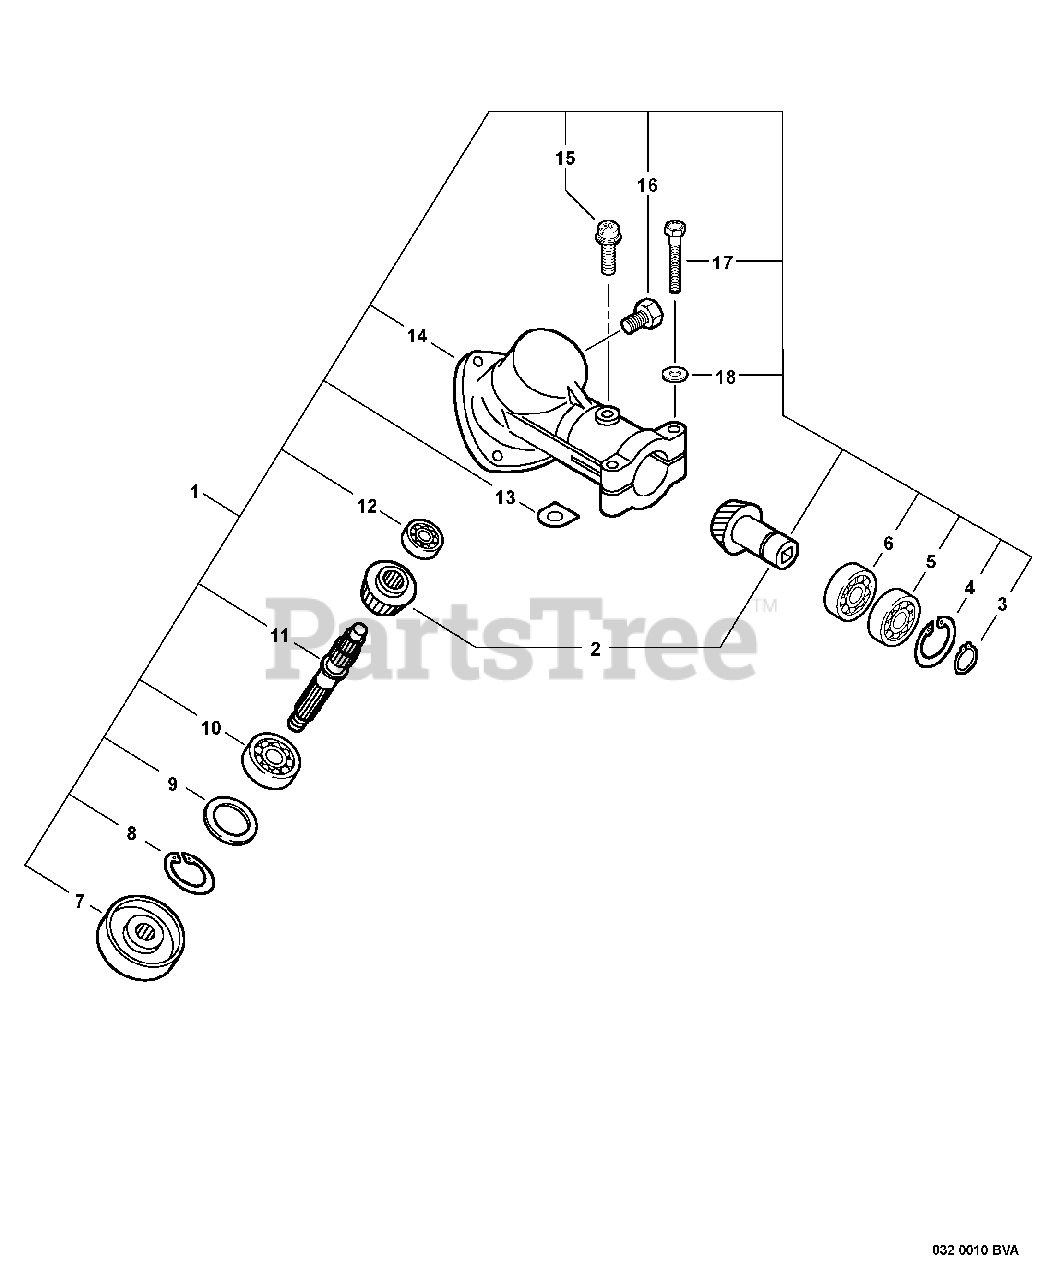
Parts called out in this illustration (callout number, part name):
1	GEAR CASE ASSY
2	GEAR SET - BEVEL
3	RING, RETAINING - 10
4	RING, RETAINING - 22
5	BEARING, BALL - 6900Z
6	BEARING, BALL - 6900
7	ADAPTOR, BLADE - UPPER
8	RING, RETAINING - 32
10	BEARING, BALL - 6201
11	GEAR - SHAFT
12	BEARING, BALL - 609
14	CASE, GEAR
15	SCREW - 5X10
16	BOLT - 8X8
17	BOLT - 5X35
18	WASHER - 5
